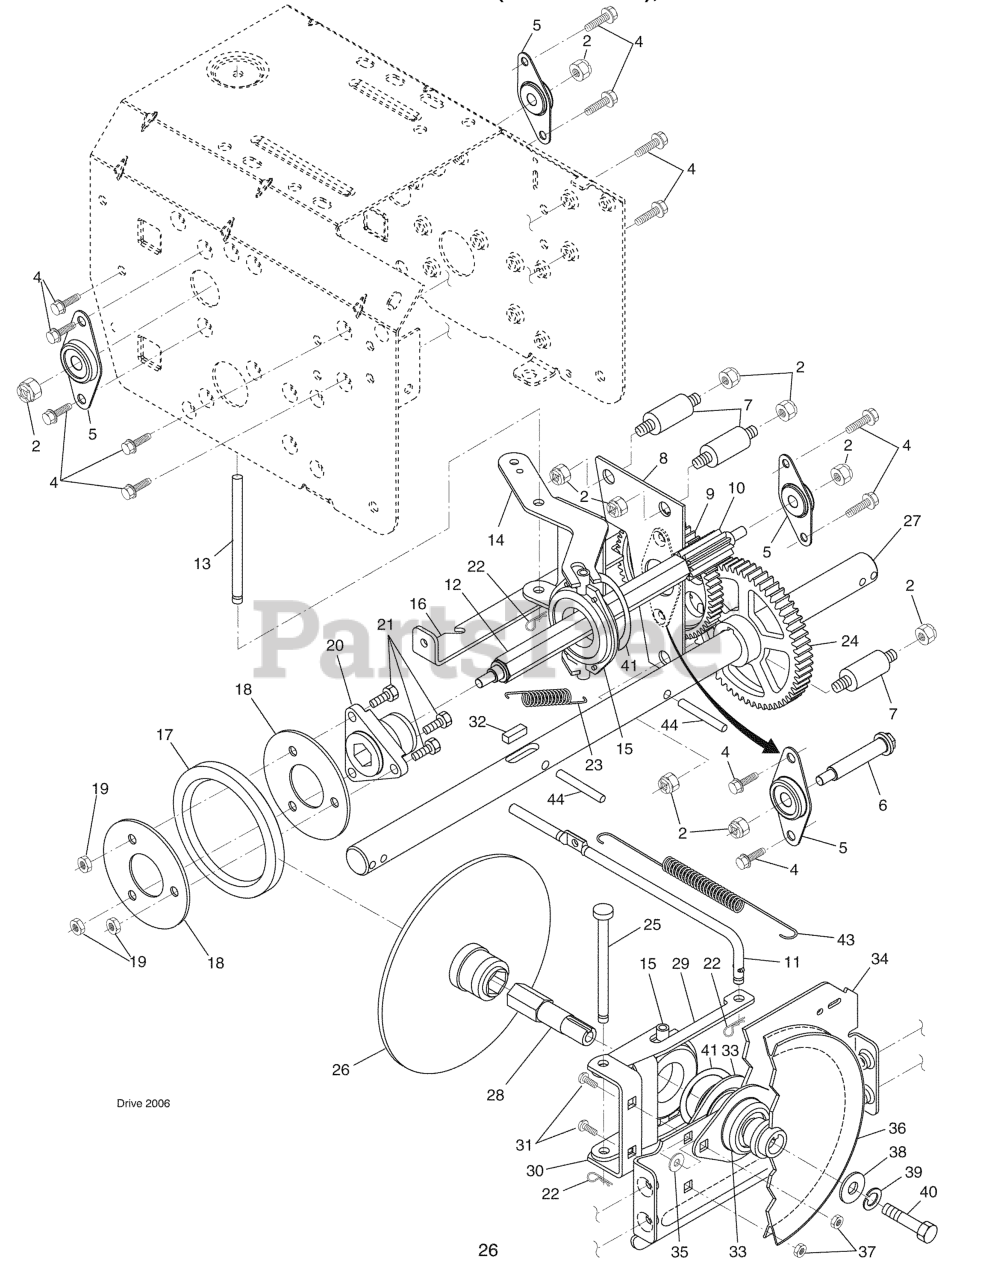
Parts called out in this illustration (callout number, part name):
2	NUT.LOCK.5/16-18
4	Screw, Hex Head 5/16-18 x 1/2
5	BEARING, FLANGE
6	SHAFT, AUXILIARY
7	SPACER, PLATE
8	AUXILLARY PLATE
9	GEAR, INTERMEDIATE
10	GEAR, PINION
11	ROD.CLUTCH.YELLOW.ZINC(VT)
12	SHAFT.HEX.LONG
13	PIN, PIVOT
14	LEVER, SPEED CONTROL
15	TRUNNION BEARING ASSY
16	BRACKET, PIVOT, SHIFT
17	RING, RUBBER WHEEL
18	PLATE.RUBBER.WHEEL
19	NUT.CENTERLOCK.5/16-
20	HUB, RUBBER WHEEL
21	BOLT
22	RETAINER CLIP PM
23	SPRING, BIAS
24	GEAR, AXLE (58T)
25	PIN, PIVOT LEVER
26	DRIVE PLATE WELDMENT
27	SHAFT.AXLE.POWER.STEERING
28	SHAFT.HEX.SHORT
29	LEVER.SHIFTER.PLATE.BLACK
30	BRACKET, SHIFTER SUPPORT
31	BOLT
32	KEY, SQUARE 1/4 X .875
33	BEARING FLANGE
34	PLATE.DRIVE.MOUNTING.BLACK
35	SPACER, BEARING
36	PULLEY.TRACTION.7.75
37	NUT.FLANGE.5/16
38	WASHER, FLAT
39	WASHER.LOCK.HVY.HLCL.SPR.5/16
40	Screw, Hex Head 5/16-18 x 3/4
41	RETAINING RING (2 2)(3 2)
43	SPRING.RETURN
44	PIN.ROLL.3/16
